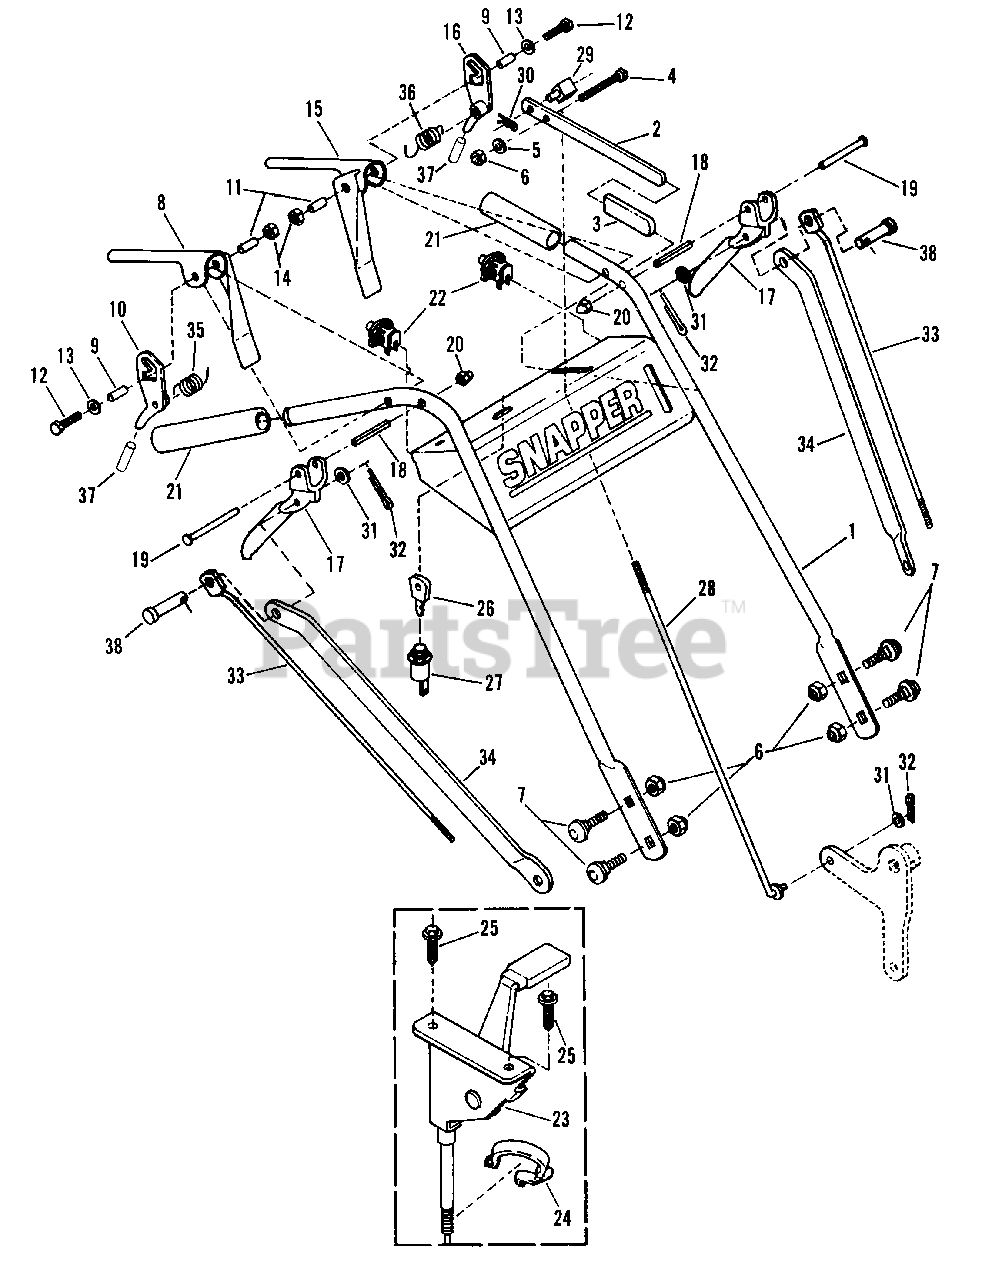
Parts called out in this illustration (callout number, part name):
1	HANDLE, Pistol Grip
2	LEVER, Blade Engagement
3	GRIP, Lever
4	SCREW, 3/8-16 x 3" Hex Head Cap
5	WASHER, 3/8" Flat
6	NUT, 3/8-16 HEX NYLON LOCK
7	BOLT, 3/8-16 x 1" Short Neck Carriage (Grade 2)
8	GRIP, Pistol OPC (Right Hand)
9	SPACER, OPC
10	LATCH (Right Hand)
11	SPACER, Brake
12	SCREW, 1/4-20 x 2-3/4" Hex Head Cap
13	WASHER, 1/4 Flat
14	NUT, 1/4-20 Hex Lock
15	GRIP, Pistol OPC (Left Hand)
16	LATCH (Left Hand)
17	LEVER, Drive (With Grip)
18	PIN, 5/16 x 1-1/8" Roll
19	PIN, 3/16 x 1-3/4" Clevis
20	NUT, 3/16 Push
21	GRIP, Handle
22	SWITCH, Seat
23	CONTROL, Throttle
24	CLIP, Throttle
25	SCREW, #10-24 x 1/2" Hex Washer Self-Tap (Torx)
26	KEY, Switch (With Cover)
27	SWITCH (On-Off)
28	ROD, Blade Clutch
29	SWIVEL
30	HAIR-PIN, 3/32 x 1 3/16"
31	WASHER, 3/8" USS
32	COTTER-PIN, 3/32 x 1"
33	ROD, Traction
34	STRAP, Brake (Left Side)
35	SPRING, Torsion (Left Hand)
36	SPRING, Torsion (Right Hand)
37	GRIP
38	PIN, 5/16 x 2" Reverse
